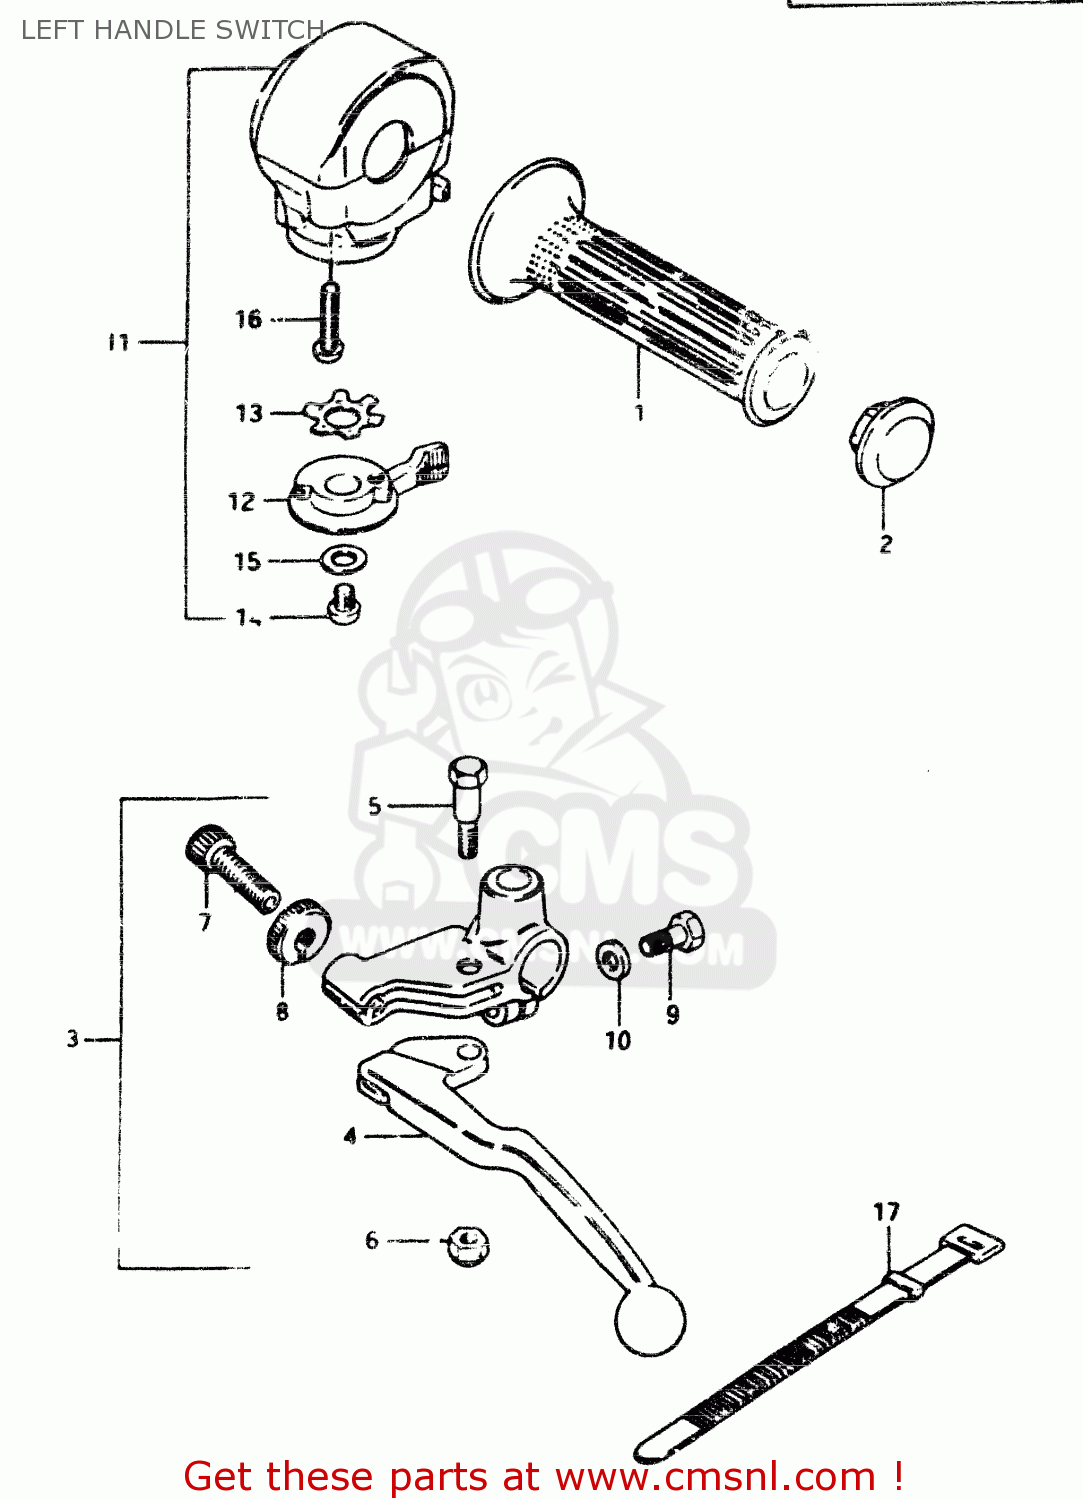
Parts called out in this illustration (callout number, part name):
1	GRIP,LEFT
2	CAP,GRIP END
3	LEVER ASSEMBLY,CLUTCH
4	LEVER,CLUTCH
5	BOLT,LEVER
6	NUT 6MM
7	ADJUSTER,CABLE
8	NUT,CABLE ADJUSTER LOCK
9	BOLT,CLUTCH LEVER HOLDER
10	SPACER
11	SWITCH ASSY, HANDLE LH
12	LEVER,STARTER
13	WASHER
14	SCREW
15	WASHER 6MM
16	SCREW
17	CLAMP(L:120)
